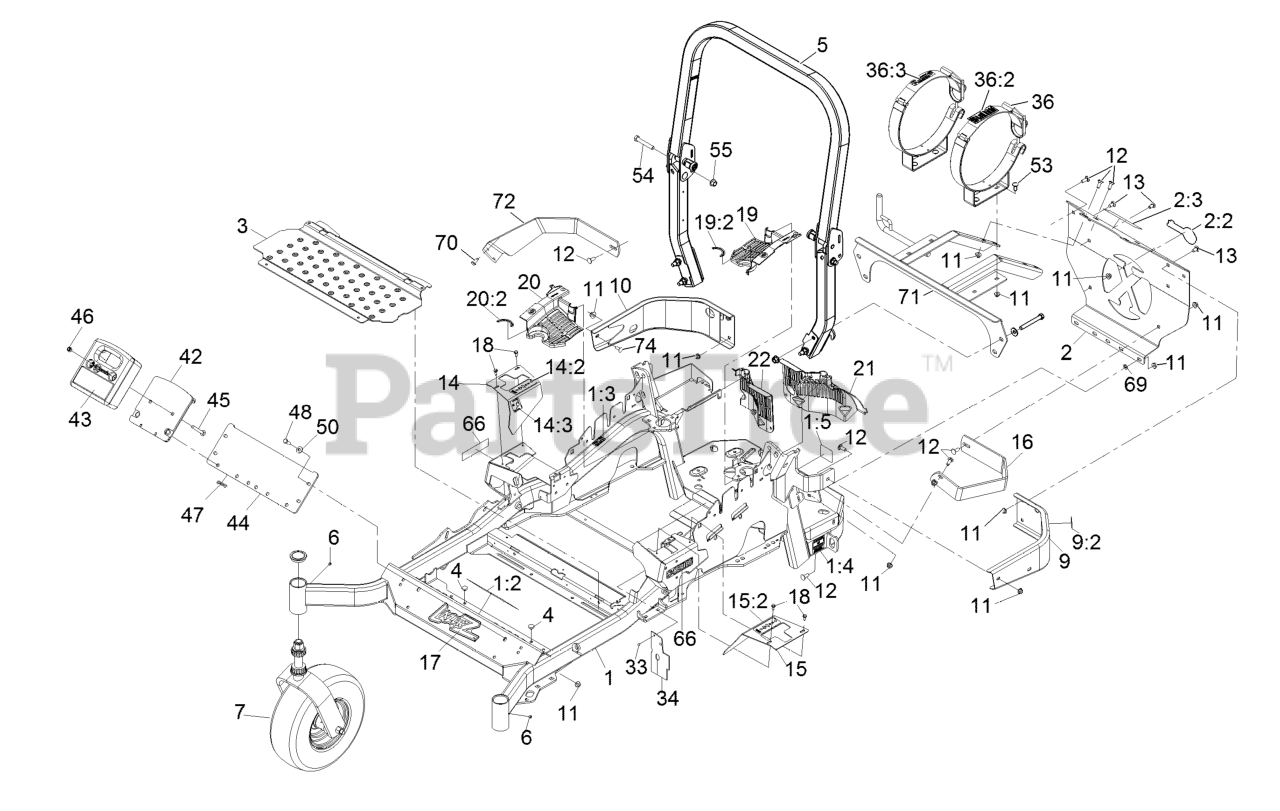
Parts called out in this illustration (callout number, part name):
1	MAINFRAME ASM
1:2	DECAL-CAUTION
1:3	DECAL-SLOPE
1:4	DECAL-BELT DRIVE
1:5	DECAL-SPARK ARRESTER
2	REAR GUARD-LP W/DECALS
2:3	DECAL-TANK REPLACEMENT
5	ROPS ASM
7	Caster Wheel Asm
9	LH BUMPER ASM
9:2	DECAL-CAUTION
10	BUMPER-RH
11	NUT-HF, NI
12	SCREW-CARR
13	SCREW-CARR
14	RH MOTION CONTROL COVER ASM
14:2	DECAL-MOTION CONTROL
14:3	DECAL-PARK BRAKE
15	LH MOTION CONTROL COVER ASM
15:2	DECAL-MOTION CONTROL
17	DECAL,LAZER MODEL
18	SCREW-HWH
19	LH HYDRO GUARD ASM
19:2	DECAL-HYDRO OIL
20	RH HYDRO GUARD ASM
20:2	DECAL-HYDRO OIL
21	GUARD-HYDRO, REAR (LH)
22	GUARD-HYDRO, REAR (RH)
33	RIVET-POP
34	DEFLECTOR-AIR FLOW
36	TANK BRACKET ASM (SET)
36:2	DECAL-LPG WARNING
36:3	DECAL-LPG 43.5LB TANK
42	WLD,WEIGHT MOUNT
43	WEIGHT,CAST 36LB
44	PLATE,WEIGHT ASM MOUNT
45	SCREW-CARR
46	NUT-LOCK, NI
47	PIN-HAIR
48	SCREW-HH
50	WASHER-BELLEVILLE
53	BOLT-CARR
54	SCREW-HH
55	Nut-Lock 1/2-13
66	DECAL-S-SERIES
69	NUT-PUSH
70	Screw-HWH 5/16-18 X 3/4 Tf
71	SUPPORT-TANK
72	STRAP-GUARD
74	BOLT-CARR
